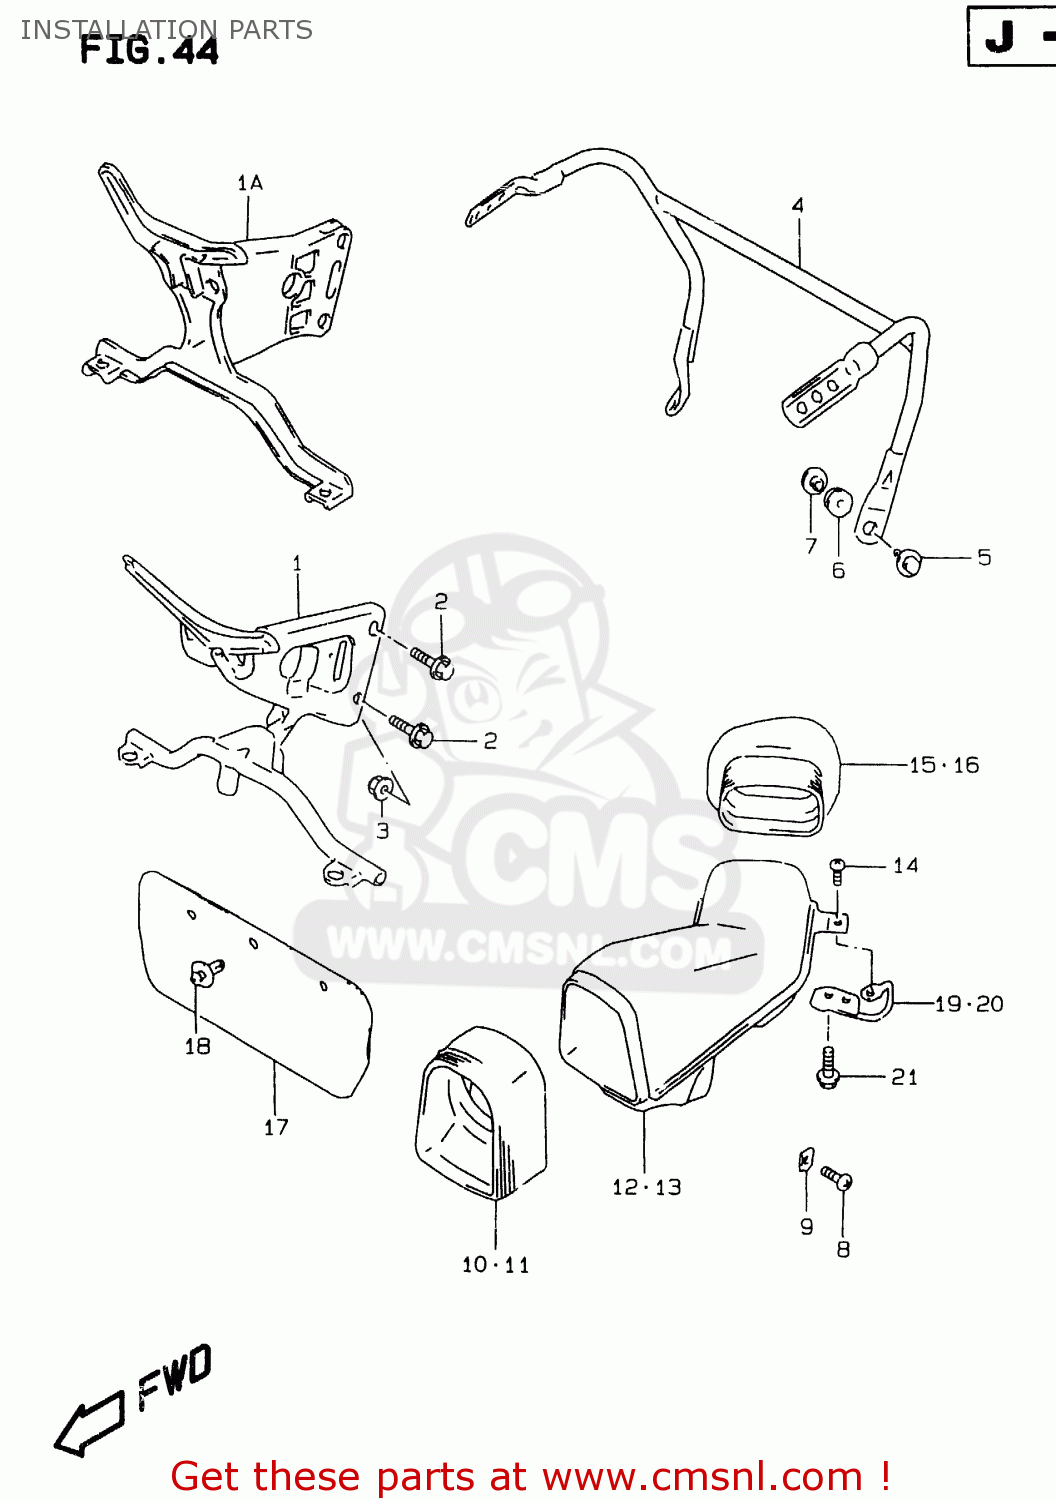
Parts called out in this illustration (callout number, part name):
1	BRACE,COWLING
1A	BRACE,COWLING
2	BOLT
3	NUT
4	BRACE COMP,REAR VIEW MIRROR
5	BOLT(6X25)
6	CUSHION
7	WASHER,MIRROR BRACE,IN
8	SCREW(5X16)
9	NUT,HEADLAMP HOUSING,UPPER
10	JOINT,AIR INTAKE,FR,R
11	JOINT,AIR INTAKE,FR,L
12	PIPE,AIR INTAKE,RIGHT
13	PIPE COMP,AIR INTAKE,LEFT
14	SCREW(5X16)
15	JOINT,AIR INTAKE,RR,R
16	JOINT,AIR INTAKE,RR,L
17	PLATE,AIR GUIDE
18	CLIP
19	BRACE,AIR INTAKE PIPE
20	BRACE,AIR INTAKE PIPE
21	BOLT
